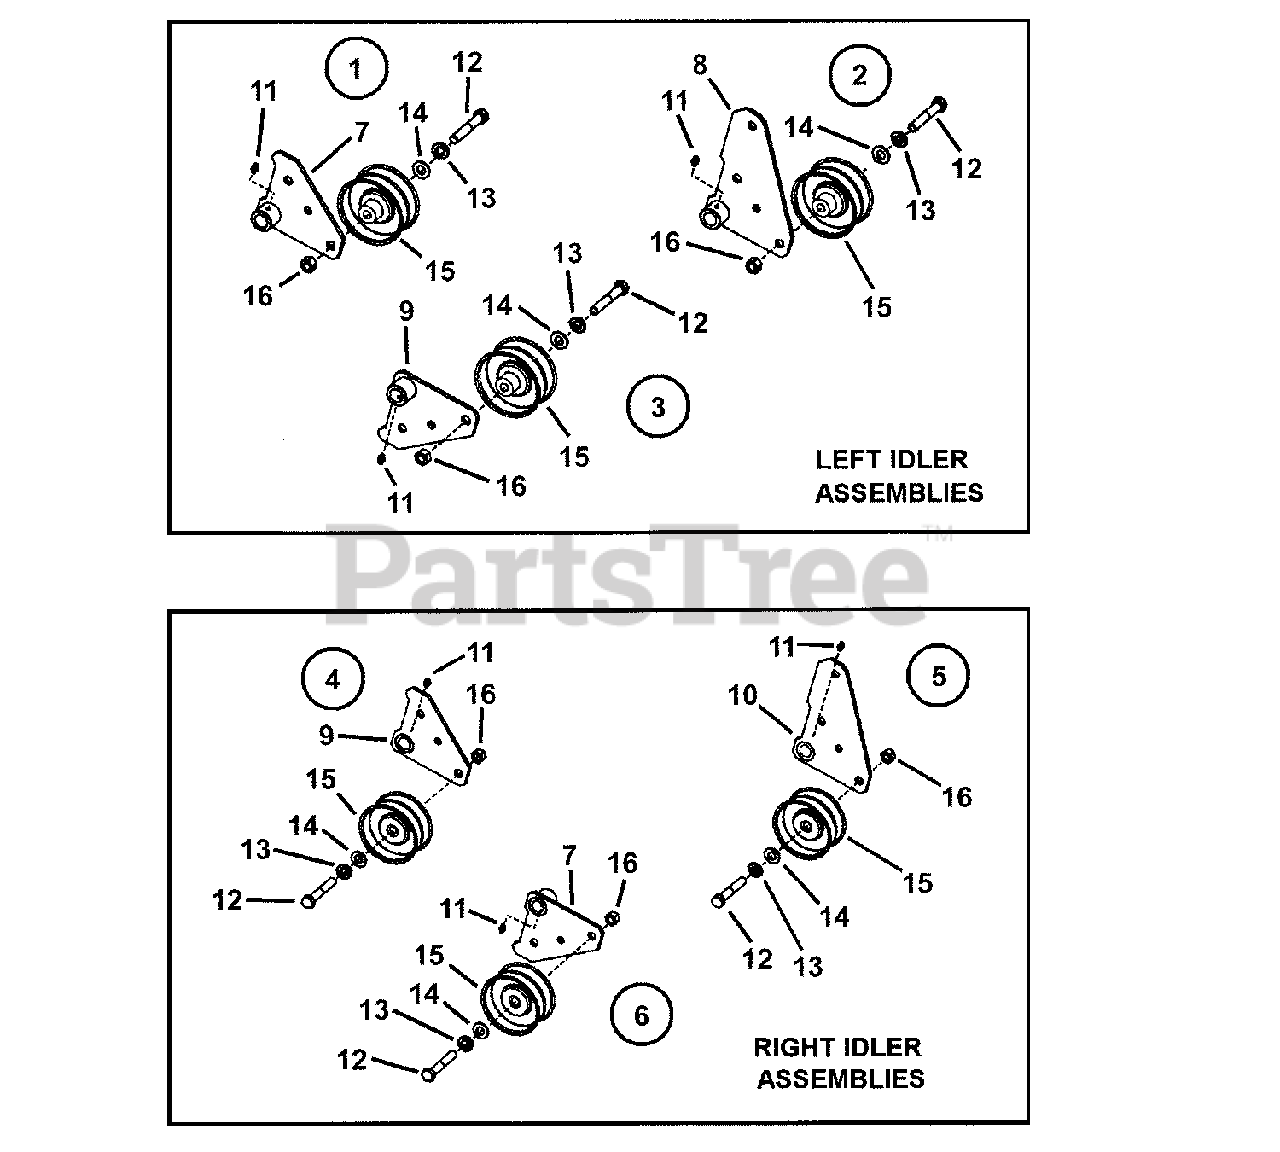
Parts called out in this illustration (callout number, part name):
1	IDLER ASSY, Upper Left
2	IDLER ASSY, Upper Left
3	IDLER ASSY, Lower Left
4	IDLER ASSY, Upper Right
5	IDLER ASSY, Upper Right
6	IDLER ASSY, Lower Right
7	WELDMENT, Idler Arm, UL/LR
8	WELDMENT, Idler Arm
9	WELDMENT, Idler Arm, UR/LL
10	WELDMENT, Idler Arm
11	LUBE FITTING, 3/16 Press-In
12	SCREW, 3/8-16 x 2-1/4" Hex Head Cap, GR 5
13	WASHER, 3/8" SPLIT LOCK
14	WASHER, 3/8" SAE Flat
15	PULLEY- Idler 3-1/4"
16	NUT, 3/8-16 Hex, GR 5 or B
